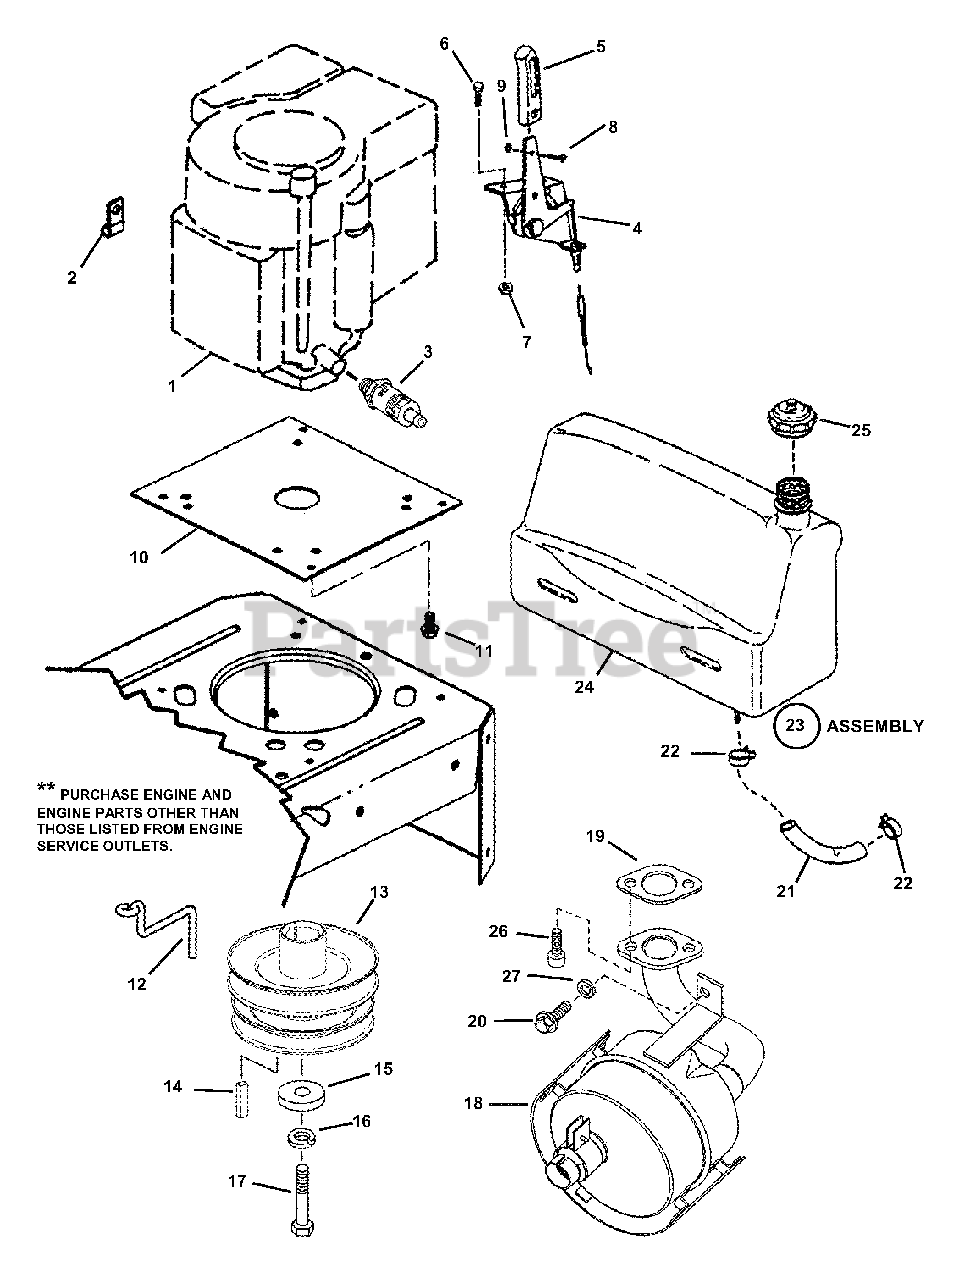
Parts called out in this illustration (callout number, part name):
2	WIRE CLIP, 7/16"
3	ASSEMBLY, Oil Valve
4	CONTROL, Engine Control
5	LEVER, Engine Control
6	SCREW, #10-32 x 5/8" Hex Washer Head, Grade 5
7	NUT, #10-32 Nyloc
8	SCREW, #8-32 x 3/8" Machine
9	NUT, #8-32 Hex
10	PLATE, Engine
11	SCREW, 3/8-16 x 1" Hex Washer Head (Briggs)
12	GUIDE, Belt
13	PULLEY, Engine (Small Pulley- Down)
14	KEY, 1/4" x 2" Square
15	SPACER, Clutch
16	WASHER, 7/16" Split Lock
17	SCREW, 7/16-20 x 1-1/2" Hex Head Cap, Grade 5
18	MUFFLER, (14.5 HP Briggs)
19	GASKET, Exhaust
20	SCREW, 1/4-20 x 3/4" Self-Tapping Gr. 5
21	HOSE, Fuel 1/4" I.D. x 7"
22	CLAMP, Fuel Hose
23	ASSEMBLY, Fuel Tank
24	TANK, Fuel
25	CAP, Fuel
26	SCREW, 5/16-18 x 3/4" Socket Head Cap Gr. 8
27	WASHER, 1/4" Lock Split
